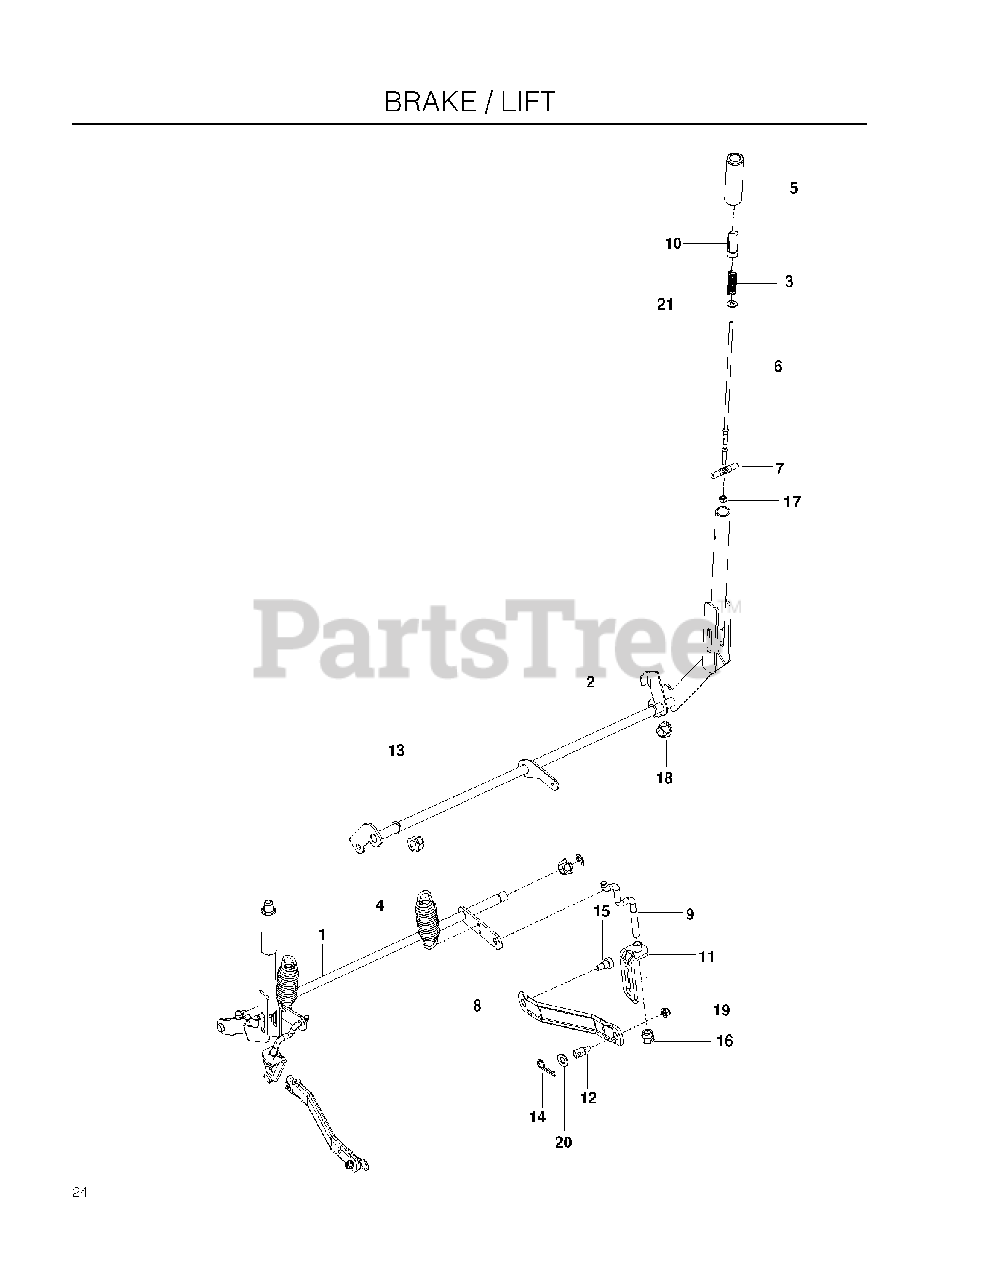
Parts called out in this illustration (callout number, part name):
1	SHAFT, LIFT, MED, BLACK
2	SHAFT ASSY, BRAKE, MED, BLK
3	SPRING, COMPRESSION
5	GRIP, HANDLE, BLACK 4"
6	ROD, HANDLE RELEASE
7	RB ROD, LATCH RELEASE
8	ARM, SUSPENSION, MOWER
9	LINK, REAR SUSPENSION
10	BUTTON, PUSH, BLACK
11	ASSEMBLY, BRKT LINK
12	STUD, FASTNER, W/ANTI-ROTATE
13	E-RING 5/8
14	HAIRPIN #4
15	SB 3/8-16 X 3/8 SKT HD ZD
16	NUT, LIFT LINK 7/16-20
17	RP_NUT 1/4-20 NYLOC
18	PLASTIC NUT
19	5/16-18 NYLOC FLANGE NUT
20	WASHER 5/8 FLAT
21	WASHER 1/4 FLAT
